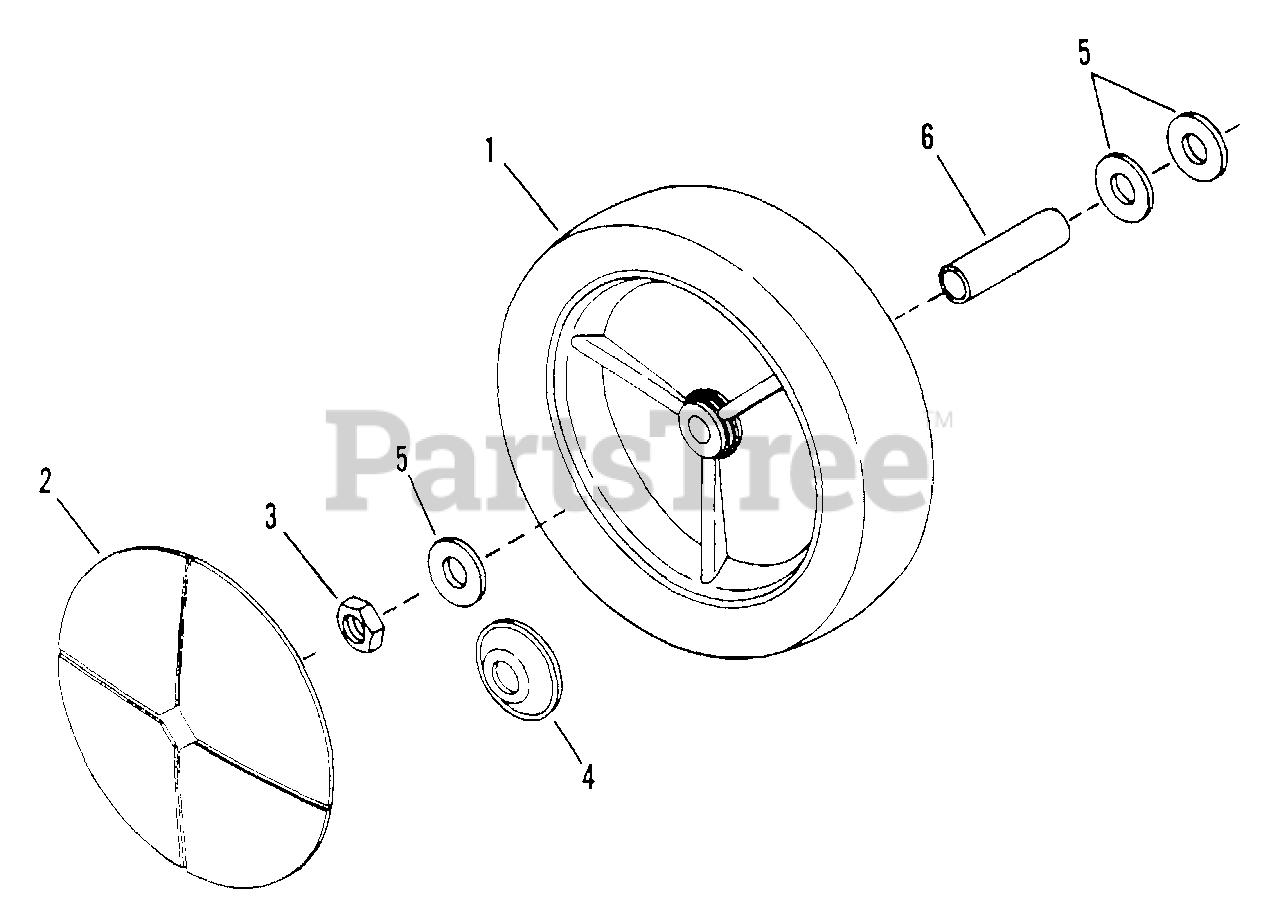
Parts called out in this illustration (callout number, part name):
1	WHEEL, 7 x 1.75 Plastic Rim
2	COVER, Wheel
3	NUT, 7/16-20 Hex Center Lock
4	CAP, Deep-Dish Hub
5	WASHER, 7/16 Flat
6	BUSHING, Axle
